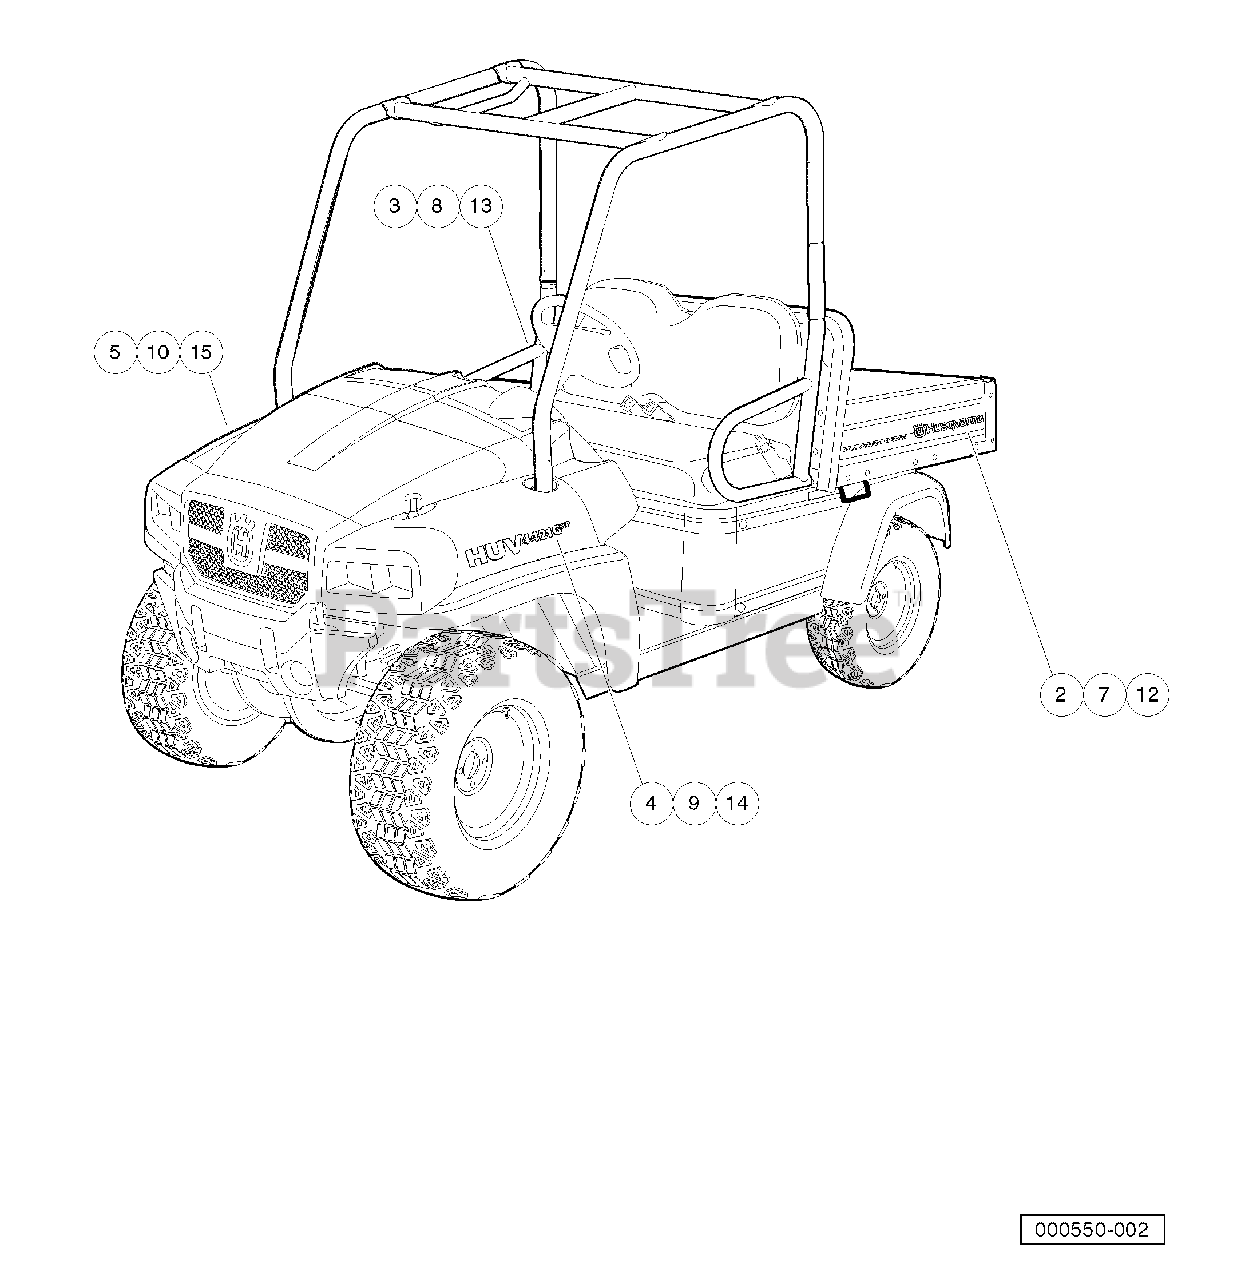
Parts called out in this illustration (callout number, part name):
1	Instl,decal,huv4421gxp,moff
2	Decal, Bed, Huv, Moff, Ds
3	Decal, Bed, Huv, Moff, Ps
4	Decal, Huv 4421gxp, Moff, Ds
5	Decal, Huv 4421gxp, Moff, Ps
7	Decal, Bed, Huv, Orange, Ds
8	Decal, Bed, Huv, Orange, Ps
9	Decal,huv 4421gxp, Orange, Ds
10	Decal,huv 4421gxp, Orange, Ps
11	Instl,decal,huv4421gxp,olv Grn
12	Decal, Bed, Huv, Olv Grn, Ds
13	Decal, Bed, Huv, Olv Grn, Ps
14	Decal,huv 4421gxp, Olv Grn, Ds
15	Decal,huv 4421gxp, Olv Grn, Ps
